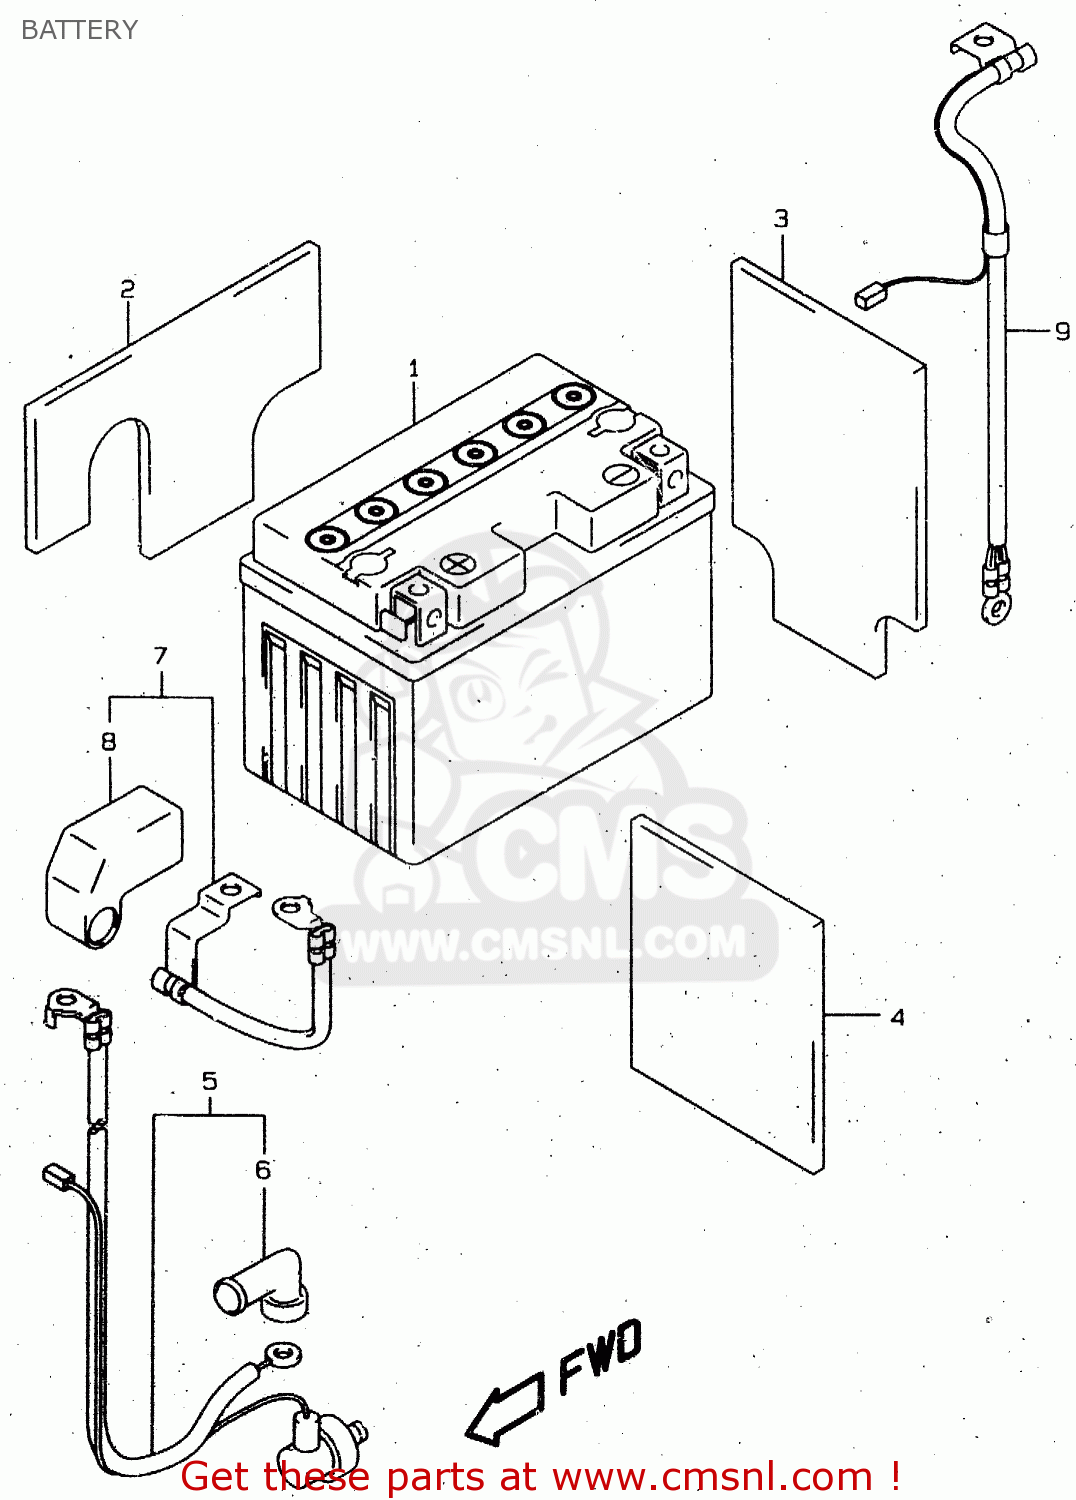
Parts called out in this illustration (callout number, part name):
1	BATTERY ASSEMBLY (12V) YT1
2	PROTECTOR(90X140X8)
3	PROTECTOR(90X140X8)
4	PROTECTOR
5	WIRE,STARTER MOTOR LEAD
6	CAP,STARTER MOTOR LEAD
7	WIRE,BATTERY PLUS
8	CAP,BATTERY PLUS
9	WIRE,BATTERY MINUS
